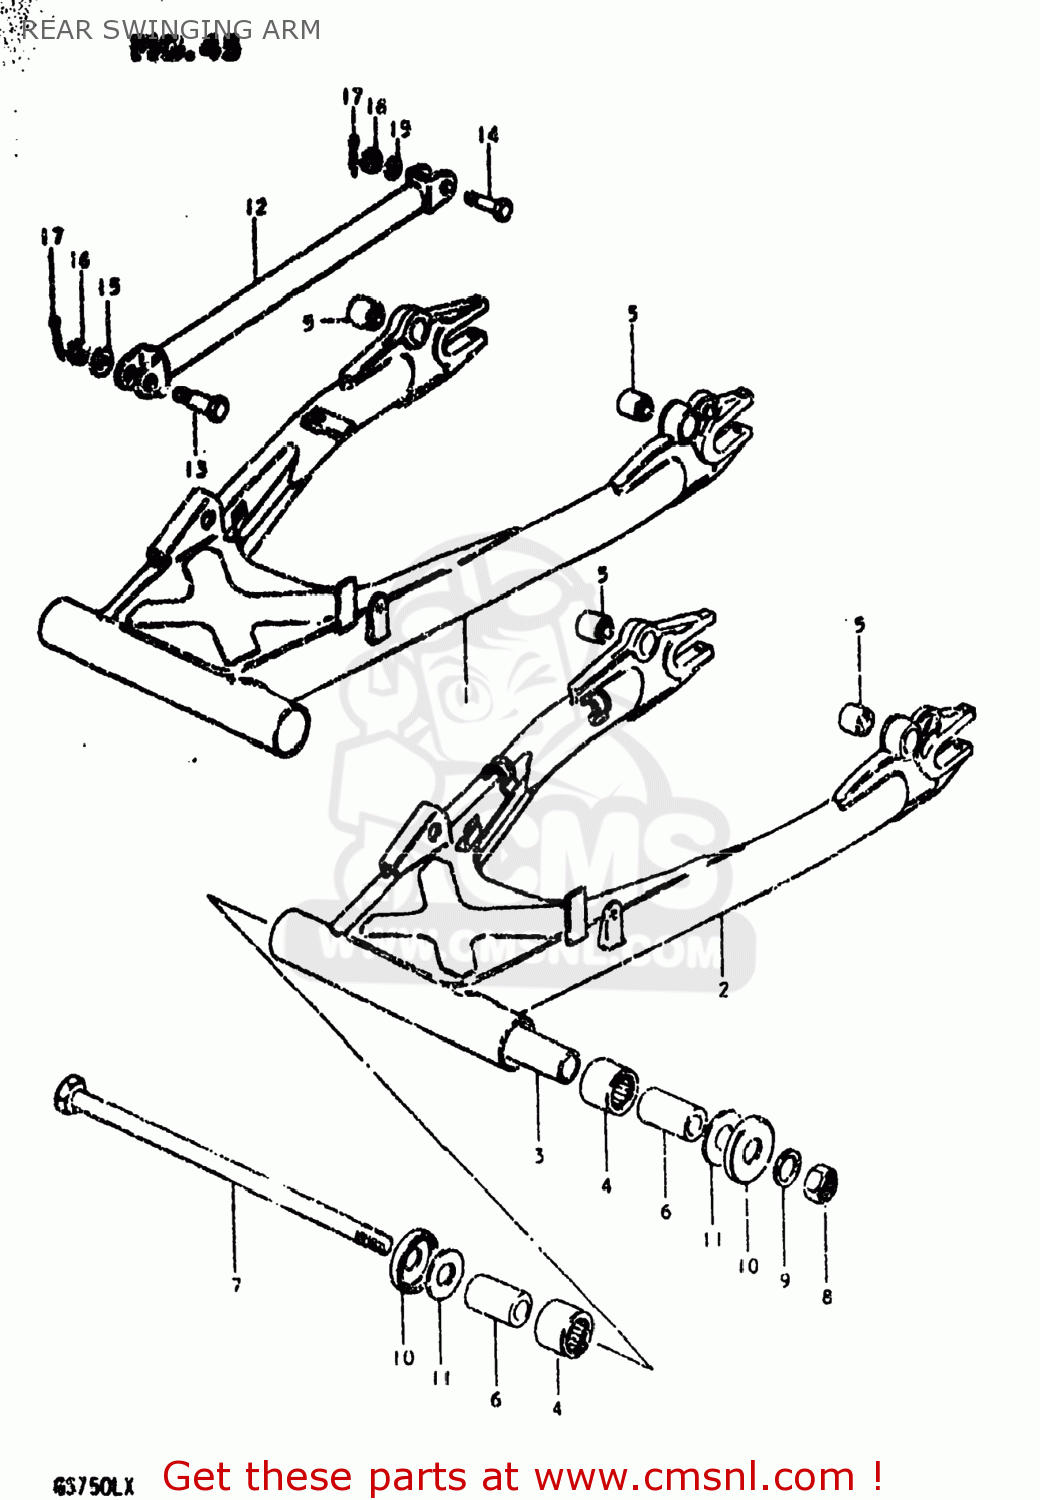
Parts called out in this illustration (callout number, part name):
1	SWING ARM ASSEMBLY,REAR
2	SWING ARM ASSEMBLY,REAR
3	SPACER,RR SWGARM PIVOT CTR
4	BEARING(22X29X30)
5	BUSH
6	SPACER,RR SWGARM PIVOT
7	SHAFT,REAR SWING ARM
8	NUT 14MM
9	WASHER
10	CVR,RR SWGARM DUST SEAL(OD:40)
11	WASHER(14.2X34X1)
12	TORQUE LINK,REAR
13	BOLT
14	BOLT(10X39)
15	WASHER
16	NUT
17	PIN 20X20
